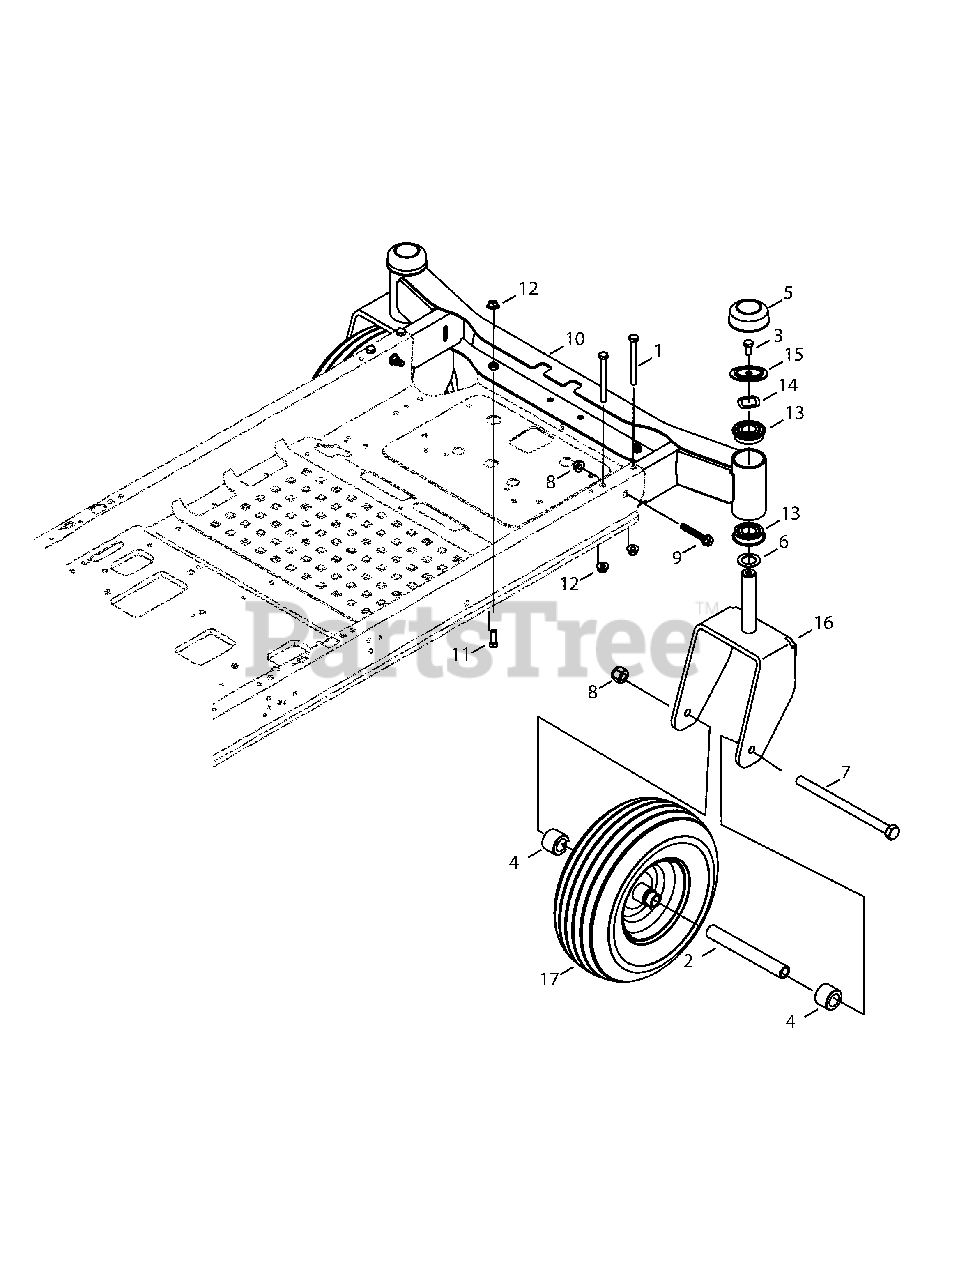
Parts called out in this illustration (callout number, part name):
1	SCREW, 3/8-16 X 3.75 GR5
3	SCREW, 3/8-16 X .75 GR 5
5	CAP, Caster Axle
6	WASHER, 1.010X1.560X.060
7	BOLT, Shoulder
9	SCREW, 3/8-16 X 2.00 GR5
10	ASSEMBLY, Front Axle
11	SCREW, 3/8-16 X 1 GR5
12	NUT, Hex Flange, Nylock, 3/8-16
13	BEARING, Ball
14	WASHER, Wave
15	SPACER, Shoulder
16	YOKE, Caster Wheel
17	WHEEL, Caster
